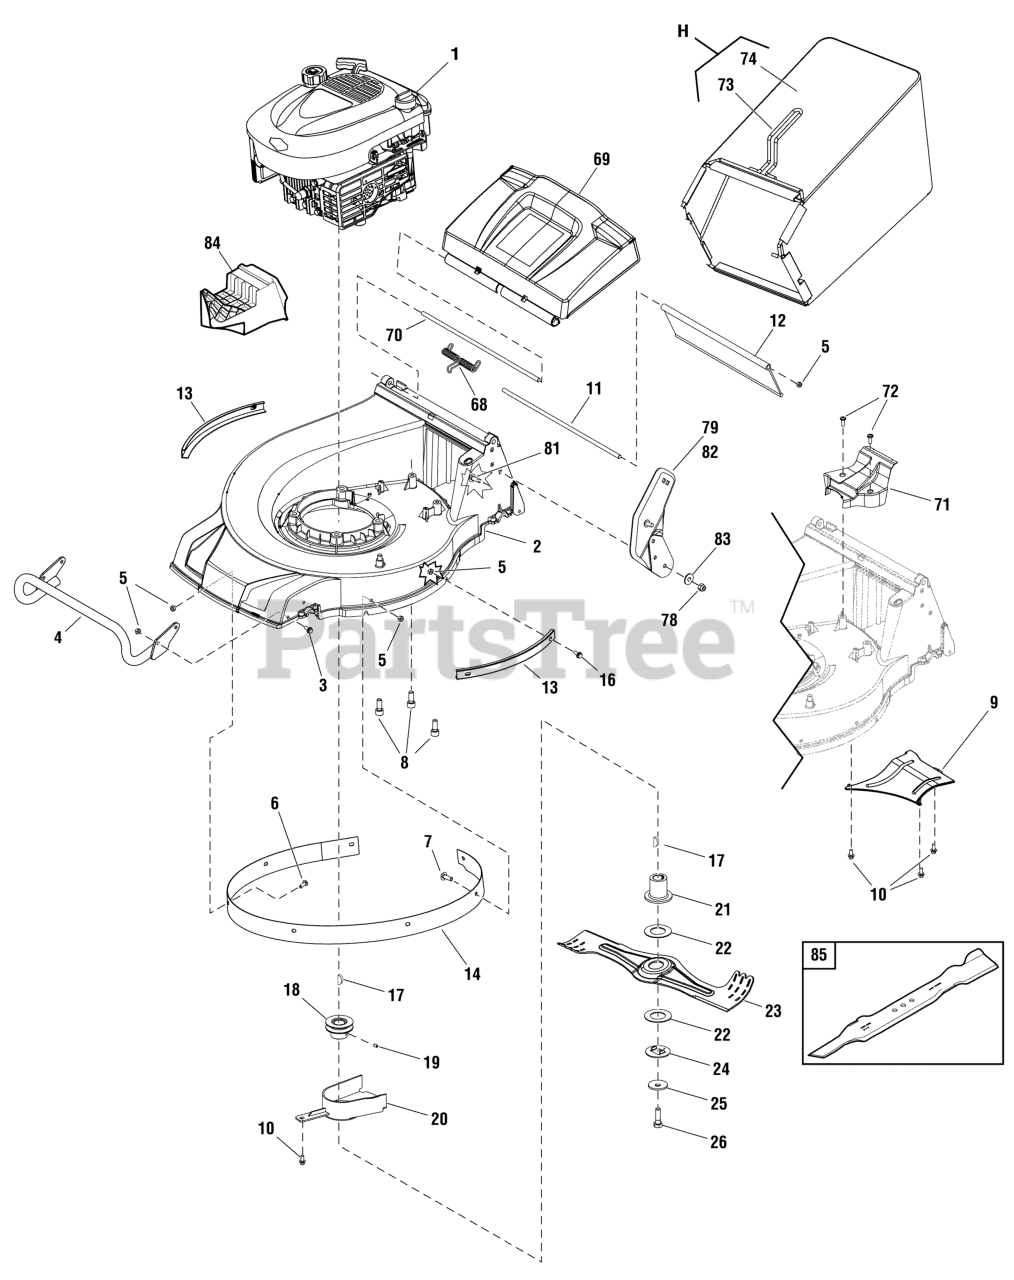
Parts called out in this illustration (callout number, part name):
1	** ENGINE, 6.75 GTP Briggs & Stratton
2	DECK, 19"
2	DECK, 21"
3	BOLT, Hex Flange
4	BUMPER, 19"
4	BUMPER, 21"
5	NUT, Hex, Nylon Insert, Torque Type
6	SCREW, Truss Head, Cross Recessed
7	SCREW, Truss Head, Cross Recessed
8	SCREW, Inner Hexagon, Round Head, Tapping
9	DEFLECTOR, Lower
10	SCREW, Hex Flange, Tapping
11	SHAFT, Rear Deflector, 19"
11	SHAFT, Rear Deflector, 21"
12	DEFLECTOR, Rear, 19"
12	DEFLECTOR, Rear, 21"
13	SHIELD, Outer
14	SHIELD, Inner Ring
16	BOLT, Hex Flange
17	KEY, Woodruff
18	PULLEY, Engine
19	SCREW, Inner Hexagon Recessed
20	SHIELD, Lower Belt
21	ADAPTOR, Blade
22	DISC, Friction
23	BLADE, 19"
23	BLADE, 21"
25	SPRING, Dishing
26	BOLT, Blade
68	SPRING, Torsion
69	COVER, Rear
70	SHAFT, Rear Cover
71	SHIELD, Upper Pulley
72	SCREW, Inner Hexagon Tapping
73	FRAME, Grass Catcher, 19" Deck
73	FRAME, Grass Catcher, 21" Deck
74	BAG, Grass Catcher, 19" Deck
74	BAG, Grass Catcher, 21" Deck
78	NUT, Nylon Insert, Torque Type
79	BRACKET, Handle, RH
81	BOLT, Carriage
82	BRACKET, Handle, LH
83	WASHER, Flat, C Class
84	PLUG, Mulch, 19"
84	PLUG, Mulch, 21"
85	BLADE, Mulch, 19"
85	BLADE, Mulch, 21"
H	GRASS CATCHER ASSEMBLY
